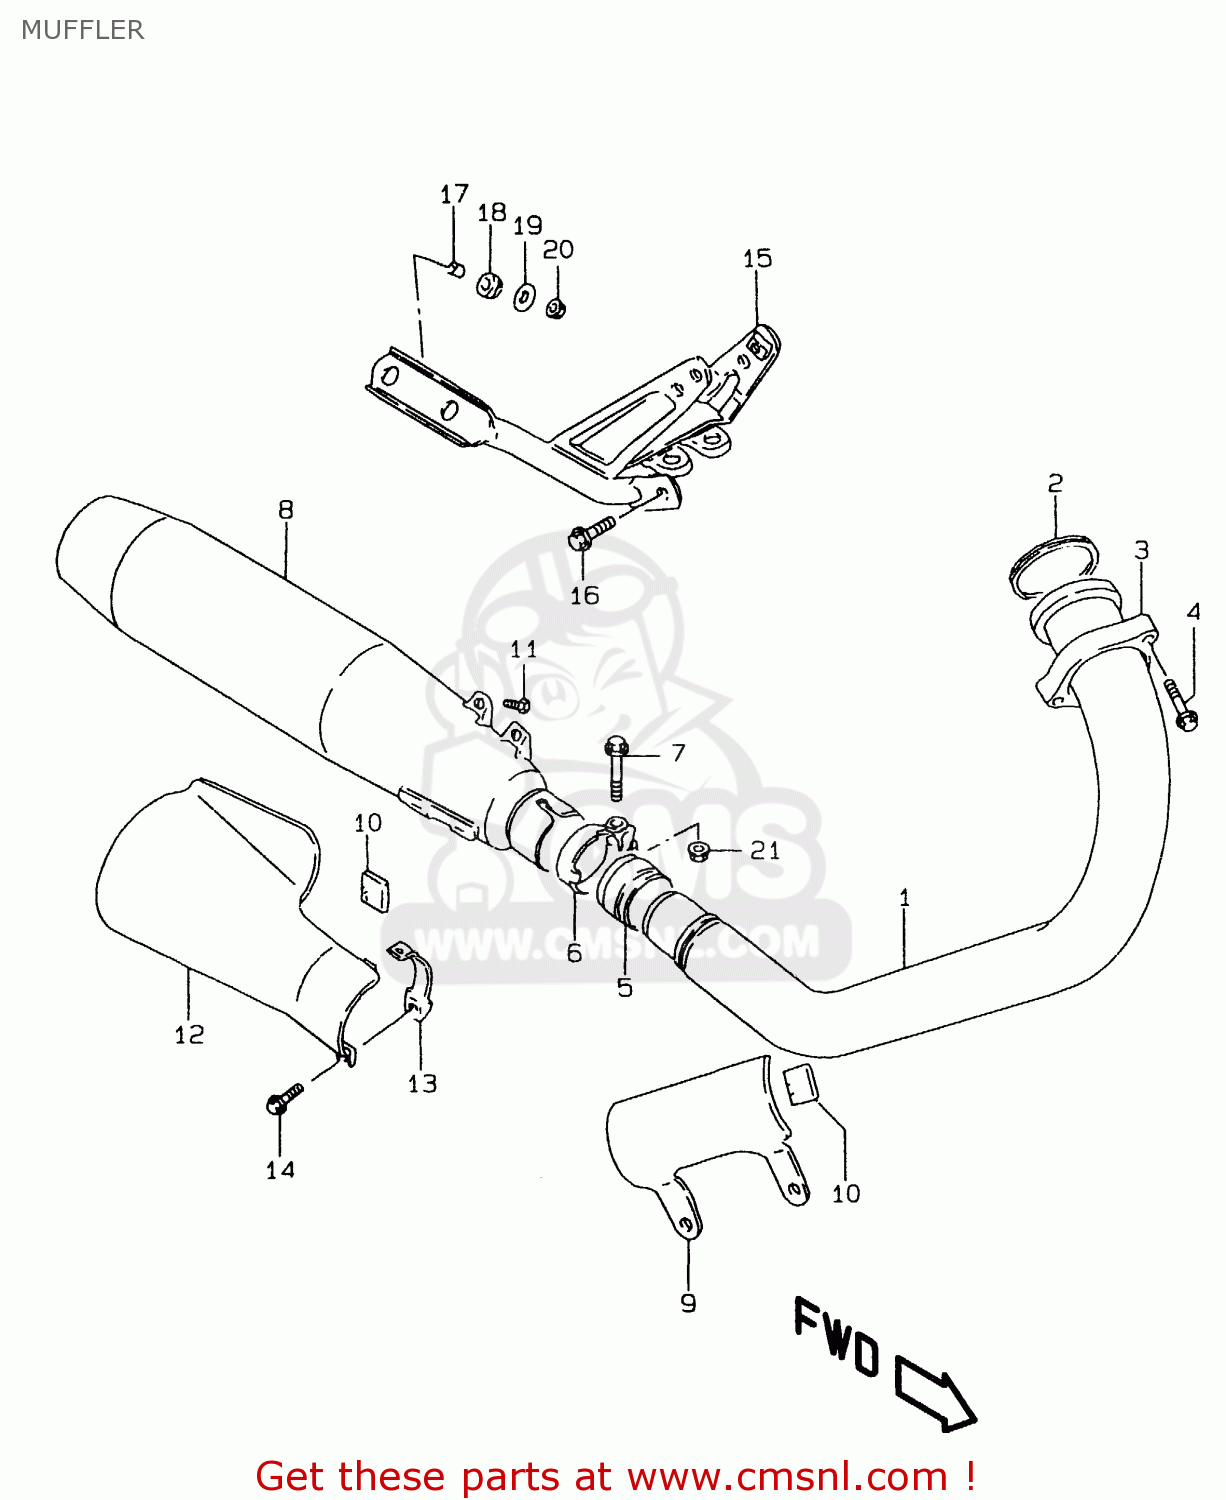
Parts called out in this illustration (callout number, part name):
1	PIPE,EXHAUST
2	GASKET,EXHAUST PIPE (NAS)
3	CLAMP,EXHAUST PIPE
4	BOLT(8X35)
5	CONNECTOR,MUFFLER
6	CLAMP,MUFFLER,R(L:42.7)
7	BOLT
8	BODY,MUFFLER
9	COVER,EXHAUST PIPE
10	GASKET (NAS)
11	SCREW
12	COVER,MUFFLER
13	CLAMP,MUFFLER COVER
14	BOLT
15	STAY,MUFFLER SUPPORT
16	BOLT
17	SPACER(8.5X12X11)
18	CUSHION
19	WASHER
20	NUT
21	NUT
